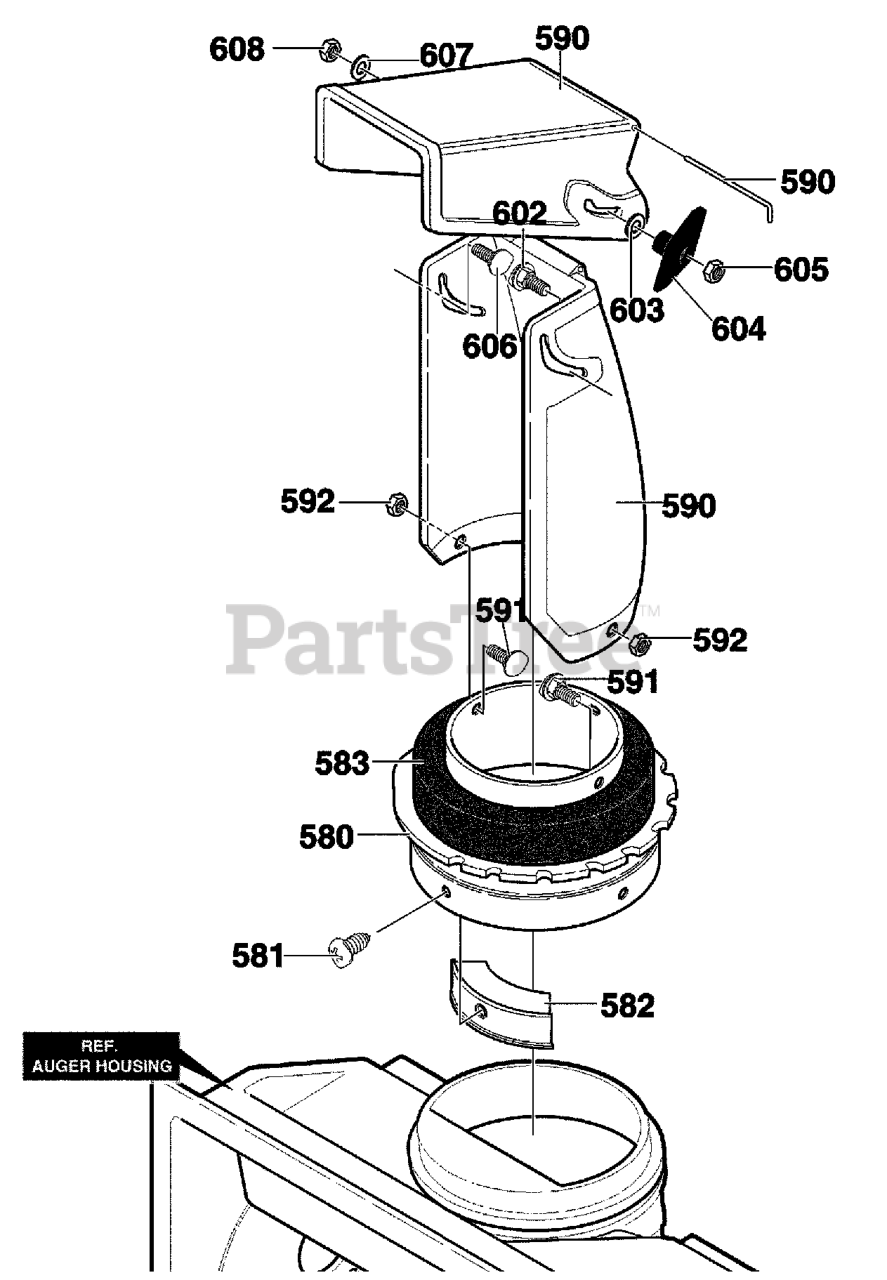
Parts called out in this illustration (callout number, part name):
580	RING, CHUTE
581	SCREW, #10X.50
582	GUIDE, CHUTE
583	DONUT FOAM
590	CHUTE ASSY.
591	SCREW 1/4-20X.50
592	NUT, 1/4-20
602	BOLT, 5/16-18X1.25 CARR.
603	WASHER, FLAT .349X.69X.066
604	KNOB, T
605	NUT, 5/16-18
606	SCREW, 5/16-18 x 0.75
607	WASHER, FLAT .349X.69X.066
608	NUT, 5/16-18
